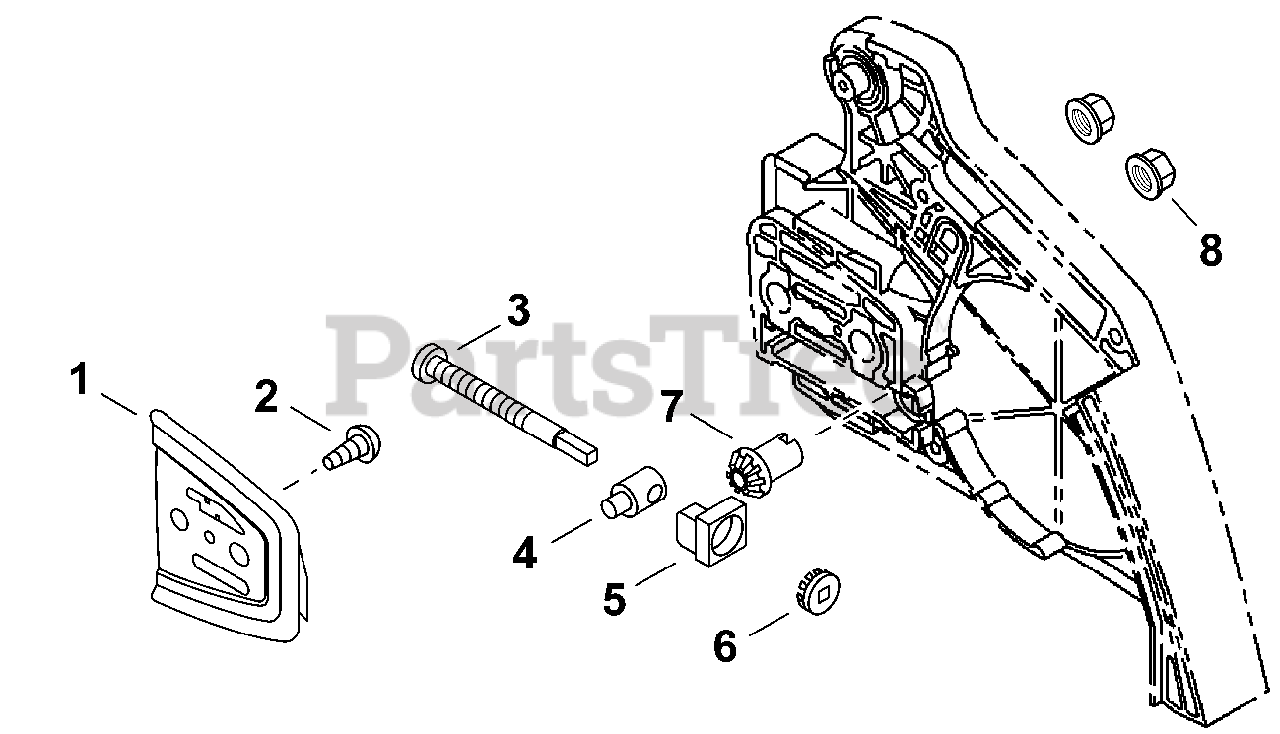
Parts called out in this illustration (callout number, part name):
1	PLATE, GUIDE - INNER
2	SCREW 4×12
3	SCREW, CHAIN TENSION
4	TENSIONER, CHAIN
5	COLLAR 8
6	GEAR, BEVEL
7	GEAR, BEVEL
8	NUT, FLANGE M8×1.25
